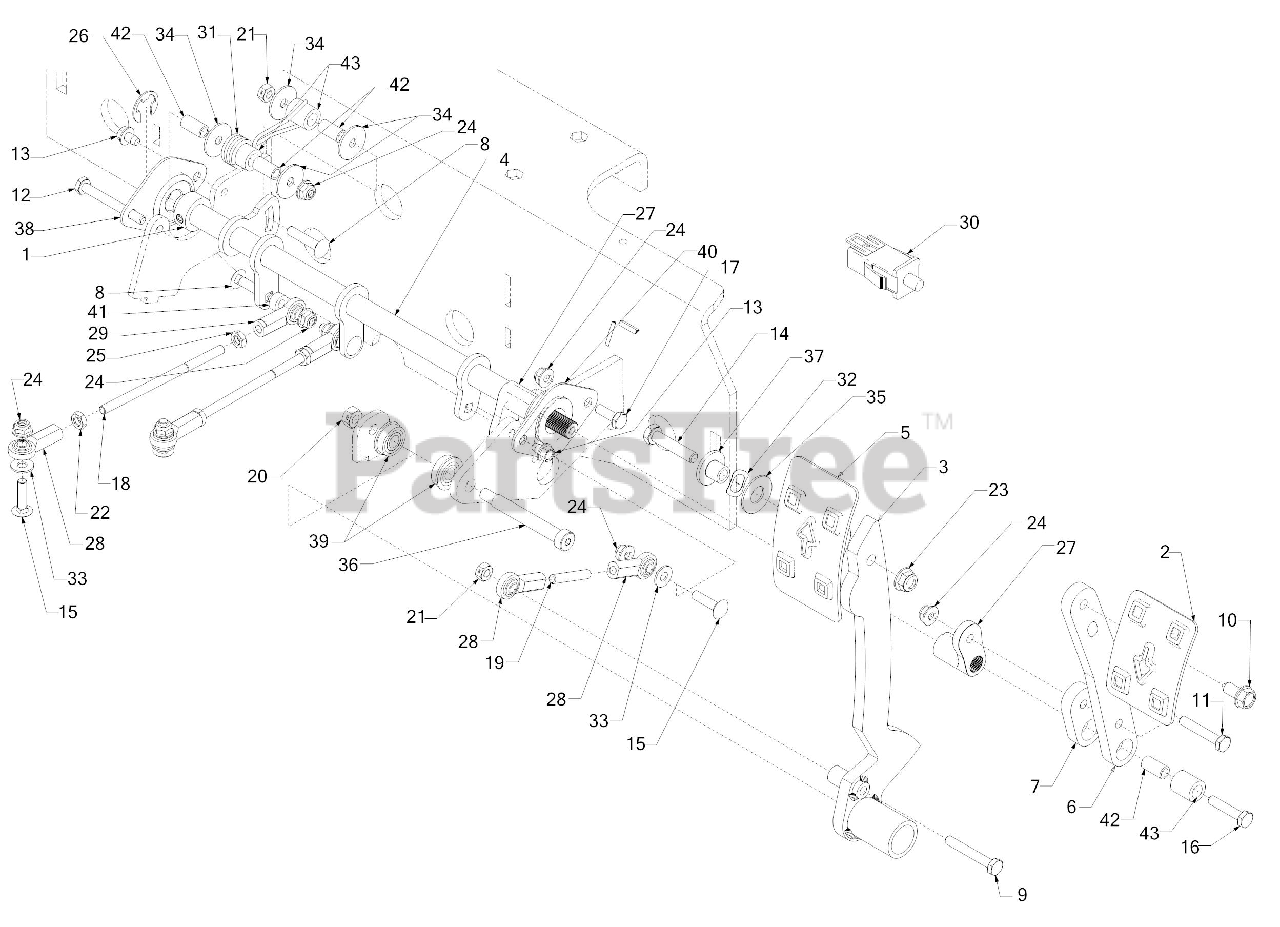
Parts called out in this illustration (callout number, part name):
1	SHAFT COLLAR .625
4	SPEED CONTROL ARM ASSEMBLY
8	CARRIAGE BOLT 1/4-20 x 1.25 Gr5
9	HEX SCREW 1/4-20 x 1.75
10	SCREW 5/16-18 x .750
11	SCREW 1/4-20 x 1.50 GR8
12	SCREW 1/4-20 x 2.25 GR5
13	SCREW 1/4-20 x .375
14	SCREW 5/16-18 x 1.5 LG
15	SCREW 1/4-20 x 1 GR5
16	SCREW 1/4-20 x 1.25 GR5
17	SCREW 1/4-20X.75 GR5
18	SPEED CONTROL ROD
19	STUD - 1/4-28
21	HEX NUT
22	HEX JAM NUT 1/4-28
23	FLANGE LOCK NUT 5/16-18
24	FLANGE LOCK NUT
25	JAM NUT 1/4-28 LH
28	END ROD (RH)
30	PLUNGER SWITCH
31	TORSION SPRING
32	WAVE WASHER
33	FLAT WASHER
34	FLAT WASHER
35	FLAT WASHER
36	SHOULDER BOLT .375 x 2.50 x 5/16-18
37	DOUBLE SHOULDER SPACER
38	BALL BEARING
39	FLANGE BEARING
40	BALL BEARING
42	SPACER .260 x .375 x .75
43	SPACER-.375X.625X.600
